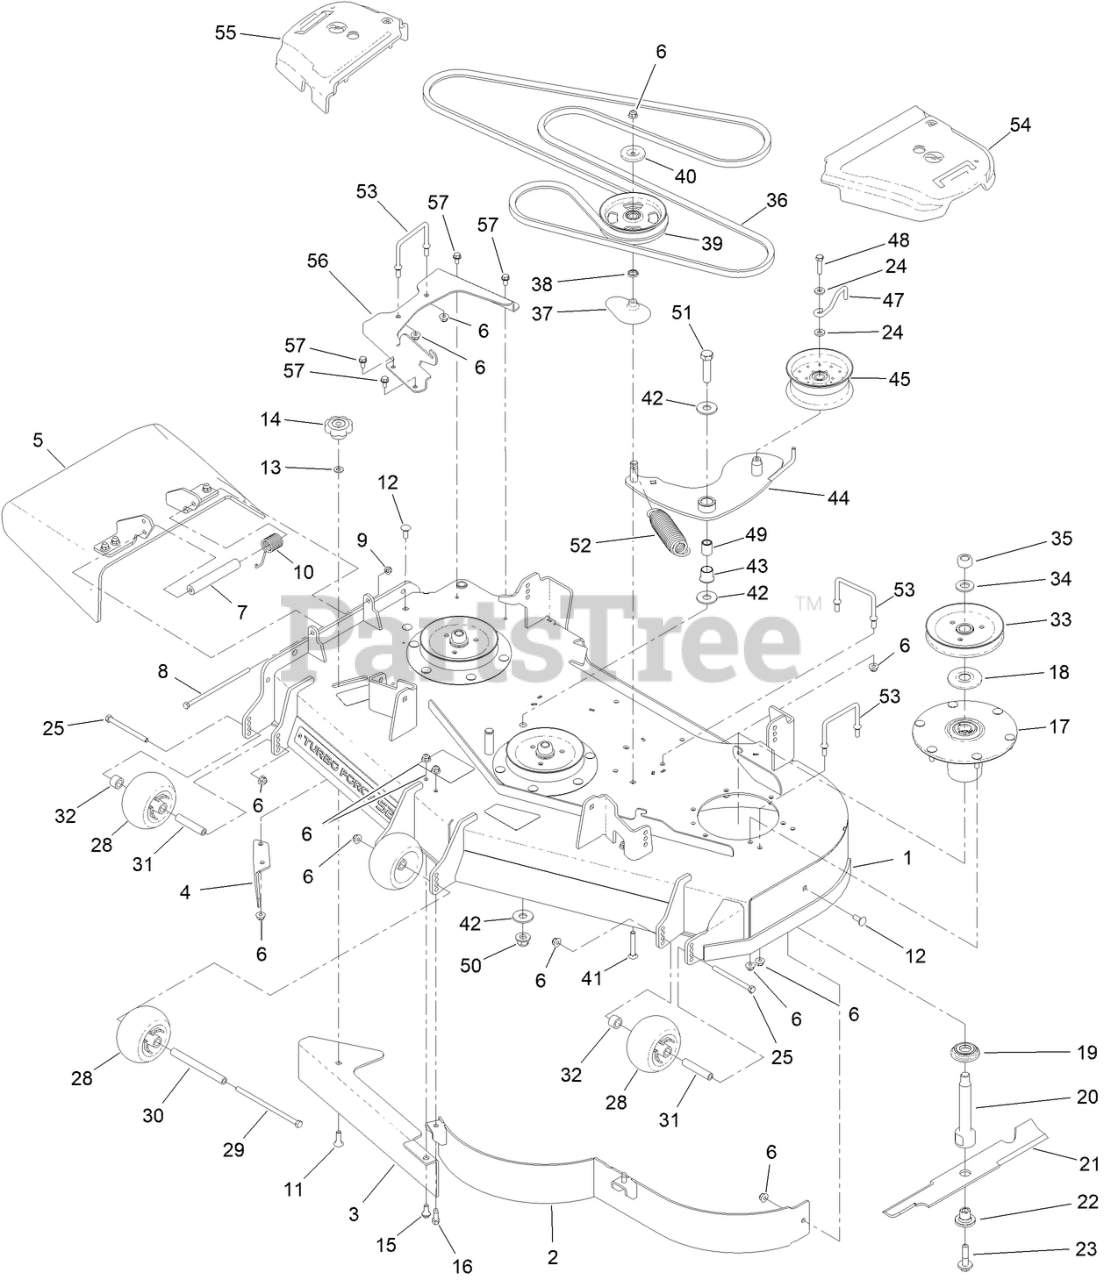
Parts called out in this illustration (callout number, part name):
1	52 DECK ASM W/DECALS
2	BAFFLE-52 INCH
3	PLATE-BAFFLE, FORMED [RED]
4	BAFFLE-DISCHARGE
5	RUBBER DEFLECTOR ASM
6	NUT-HF, NI
7	SPACER
8	SCREW-HH
9	NUT-HF, NI
10	SPRING-TORSION
11	SCREW-CARR
12	BOLT-CARR
13	WASHER-HARDENED
15	BOLT-SHOULDER
17	SPINDLE ASM
18	GUARD-BEARING, TOP
19	GUARD-BOTTOM
20	SHAFT-SPINDLE
21	BLADE-FLOW, HIGH
22	BUSHING-HEX
23	SCREW-SEMS
24	SPACER-HUB, BLOWER
25	SCREW-HH
28	ROLLER-SCALP, ANTI
29	SCREW-HH
30	SPACER-WHEEL
31	TUBE-SHAFTING
32	TUBE-SPACER
33	SHEAVE-BLADE, DRIVE
34	WASHER
35	NUT-HEX
36	BELT, 5V
37	SPACER-PULLEY
38	SPACER-PLATE, BBC
39	PULLEY-IDLER,FLAT
40	SHIELD-DUST
41	SCREW-CARR
42	WASHER-FLAT
43	BUSHING, IGUS
44	IDLER ARM ASM [BLACK]
45	IDLER-PULLEY, FLAT
47	WIREFORM BELT GUIDE,IDLER, TOP
48	SCREW-HH
49	BUSHING-IDLER PIVOT
50	NUT-HF
51	SCREW-HH
52	SPRING-EXTENSION
53	WIREFORM-COVER
54	COVER-BELT, LH
55	COVER-BELT, RH
56	PLATFORM-BELT COVER 52
57	SCREW-HWHTF
